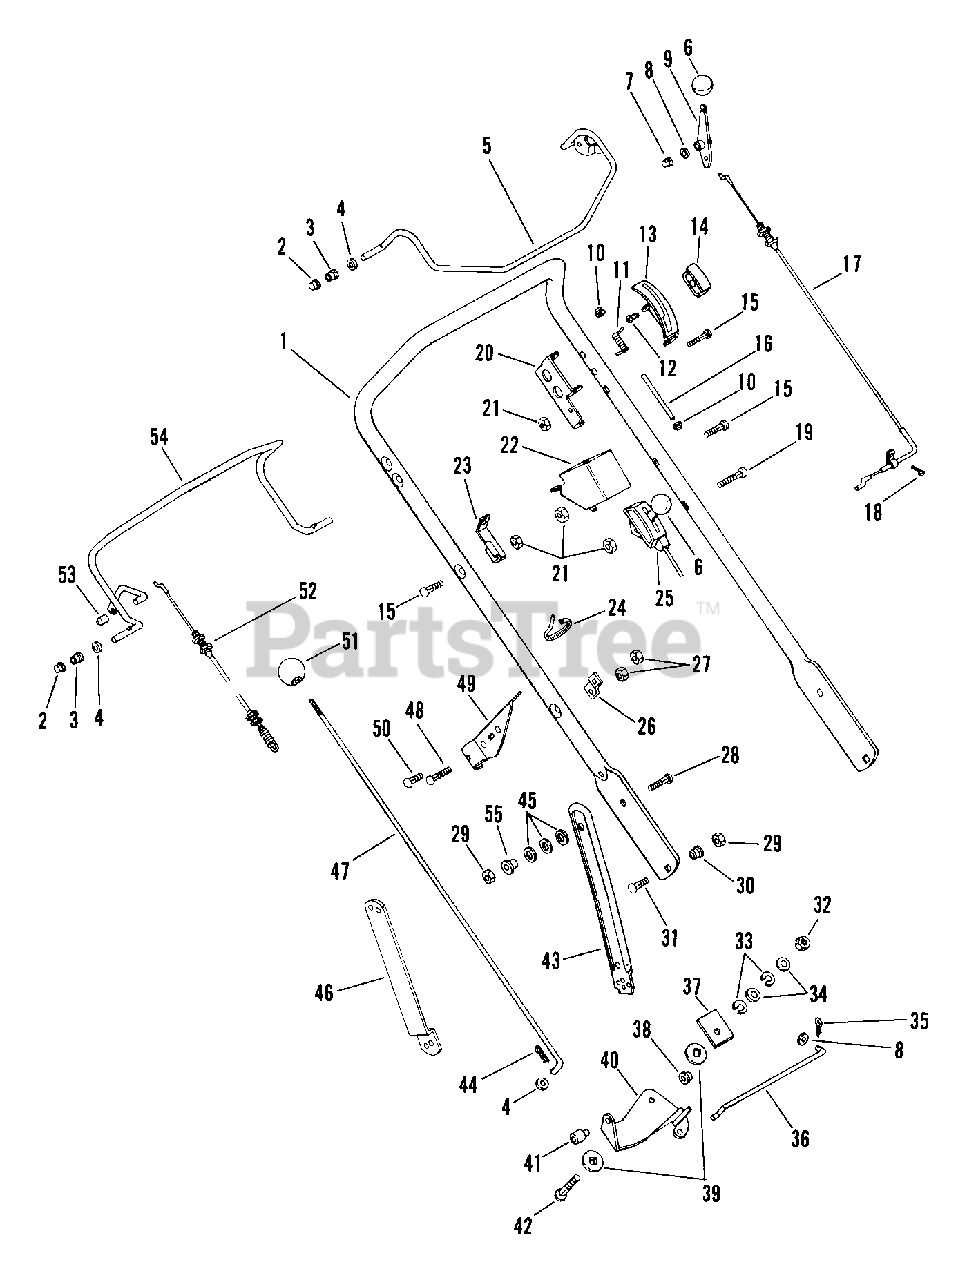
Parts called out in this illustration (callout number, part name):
1	HANDLEBAR
2	NUT-PUSH .312 DIA. PAL
3	BSHG-FLG .325X.444X.440X.560
4	WSHR-FL-STL.344X.688X.065PL
5	START BAIL WELDMENT
5	BBC BAIL
5	START BAIL WELDMENT-ELEC.
6	KNOB, CONTROL-THROTTLE
7	PUSH NUT, .25
8	WSHR-FL-STL.281X.62X.065 PL
9	START LEVER WELDMENT
10	PUSH NUT, .188
11	SG-TORS .062X.28X1.00
12	SCR-TAP 10-24X.375 CRPH PL 1A
13	BBC LATCH
14	KNOB
15	BLT-RDHDSQNK .25-20X1.25 XLGPL
16	PIN,BBC LATCH
17	CABLE,ENGINE
17	CABLE-BBC
17	CABLE-ENG. CONTROL
17	CABLE, ENGINE
18	SCR-MCH 10-32X.25 CR SEMS PL
19	BLT-RDHDXLSQNK .25-20X2.0 G5YZ
20	BBC LATCH PIVOT
21	NUT-KEPS .250-20
22	SWITCH-CABLE ANCHOR
22	SWITCH-CABLE ANCHOR WELDMENT
23	CABLE ANCHOR
23	CABLE ANCHOR-LH
24	CABLE TIE LG 5-1/2
25	CABLE,THROTTLE W/CHOKE
25	CABLE,THROTTLE
25	THROTTLE CABLE W/CHOKE
26	BRACE-SPEED CONTROL
27	NUT-LK-CTR .250-20 PL
28	BLT-RDHDSQNK .31-18X1.12 GR5PL
29	NUT-LK-TOP .312-18 GR C PL
30	BSHG, FLG .325X.499X.26X.88
31	BLT-RDHDSQNK.31-18X.88 GR5YWZC
32	NUT-LK-CTR .375-16 GR A PL
33	WSHR-LK .375X.115 HVY PL
34	WSHR-FL-STL.406X.812X.065PL
35	PIN-COTR .06X.50
36	SHIFT LINK
37	PRESSURE FLANGE
38	CAP, 3/8 ROD YWZC
39	FRICTION WASHER
40	BELL CRANK - SPEED CONTROL
41	SWIVEL
42	BLT-RDHDSQNK .38-16X1.50 PL
42	BLT-RDHDSQNK .38-16X1.25 SHTPL
43	LINK,HANDLE BAR ADJUST LH
43	LINK,HANDLE BAR ADJ RH
44	PIN-HAIR INT .08X.18X1.18
45	WASHER,BELLEVILLE SPRING
46	HANDLEBAR BRACKET
47	ROD-SPEED CONTROL
48	BLT-RDHDSQNK .25-20X1.50 SHTPL
49	BRACKET-SPEED CONTROL
50	@BLT-RHDSSQNK .25-20X.38 G2YZ
51	KNOB, BALL 5/16-18 X 1.5
52	CABLE, TRACTION
53	CAP, VINYL, .25 ID
54	TRACTION BAIL-COATED
55	BSHG-FLG .325X.500X.513X.875
56	SPACER
